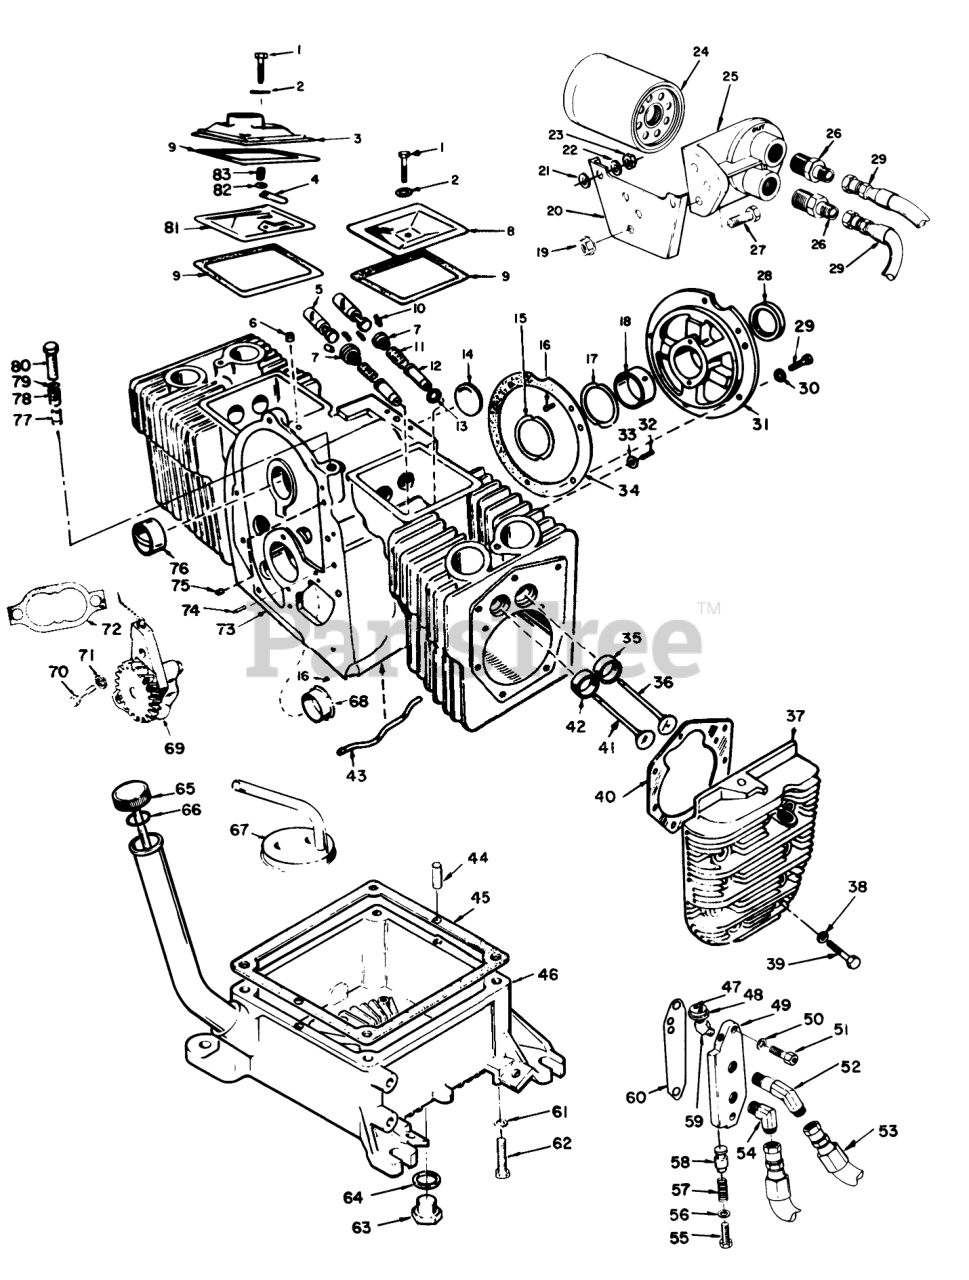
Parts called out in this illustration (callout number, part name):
1	SCREW-HH
2	WASHER
3	VALVE COVER
4	VALVE
5	TAPPET
6	PLUG-BREATHER HOLE
7	ROTOCAP
8	VALVE COVER
9	GASKET
10	LOCK (SET OF 2)
11	SPRING
12	GUIDE
13	GASKET
15	WASHER
16	PIN-DRIVE
18	Bearing, Crankshaft Rear Standard (Incl. Ref. #15)
19	SELF LOCKNUT
20	BRACKET
21	OIL SEAL
22	WASHER
23	NUT-HEX
24	FILTER-OIL
25	BASE ASM
26	MALE CONNECTOR
27	SCREW-HH
29	HEX HD CAPSCREW
30	WASHER-LOCK
31	Plate-Bearing
33	WASHER
34	GASKET
35	STD INSERT
36	VALVE
37	CYL RS HEAD
38	WASHER
39	HEX HD CAPSCREW
40	GASKET
41	EXHAUST VALVE
42	STD INSERT
43	OIL TUBE
44	DOWEL PIN
45	GASKET
46	OIL BASE ASM
48	SWITCH
49	Adapter,Oil Filter
50	WASHER
51	HEX SOCKET CAPSCREW
52	MALE CONNECTOR
53	FLEX HOSE ASM
54	MALE CONNECTOR
55	SCREW-HH
56	WASHER
57	Spring, Bypass
58	PLUNGER
59	ELBOW-45 DEG
60	Gasket
61	WASHER-LOCK
62	SCREW-HH
63	PLUG-OIL
64	GASKET
65	INDICATOR & CAP
66	SEAL 0-RING
67	OIL CUP ASM
68	KIT-BEARING, SLEEVE
70	SCREW-HH
71	WASHER-LOCK
72	GASKET KIT
73	Block Assy. (Incl. Ref. #6, 12-18, 29-31, 34-35, 42-43, 68, 74 & 76)
74	PIN-GEAR COVER
75	PLUG-CORE HOLE
76	SLEEVE-BEARING
77	PLUNGER
78	SPRING
79	WASHER
80	SCREW-HH
81	BAFFLE
82	WASHER-FLAT
83	SPRING
